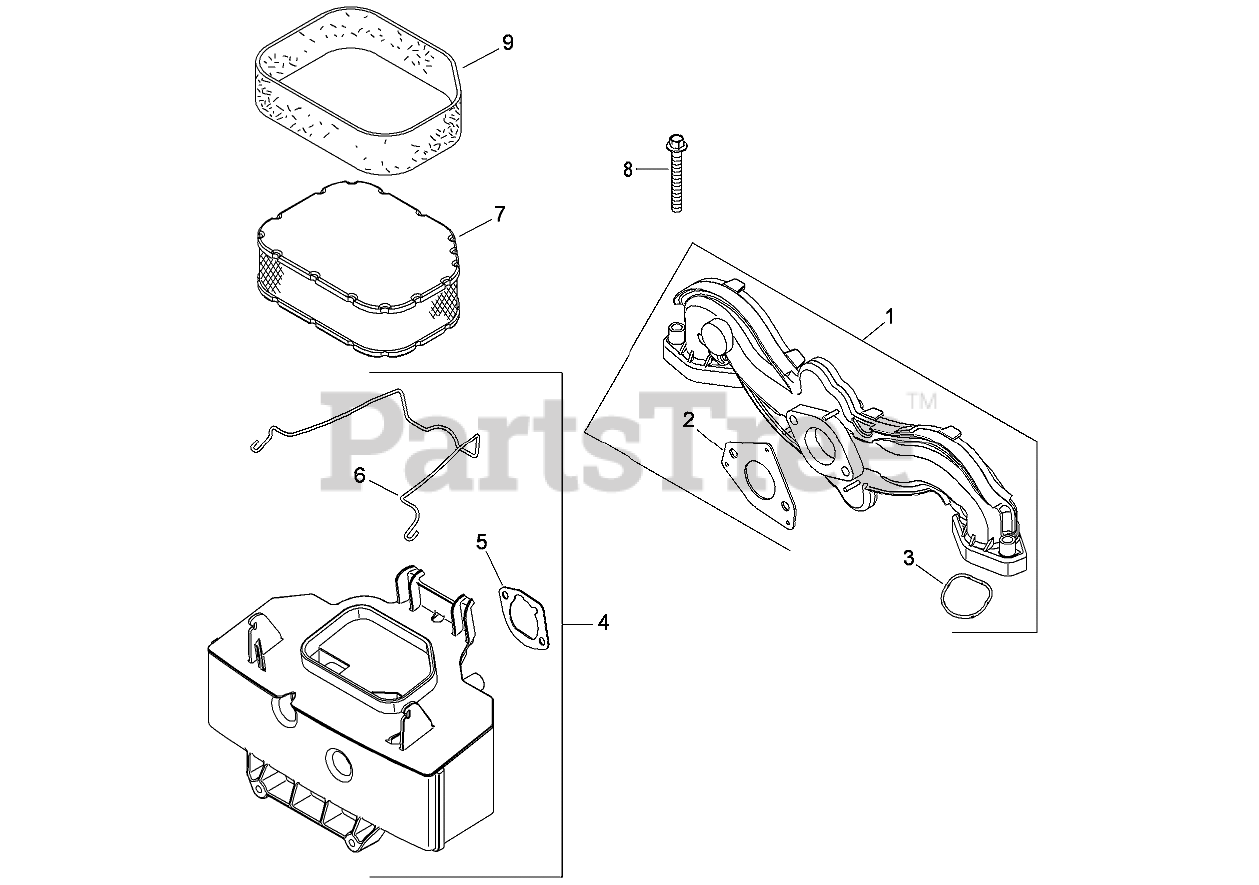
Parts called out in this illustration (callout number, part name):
1	MANIFOLD-INTAKE (INCLUDES 2, 3)
2	GASKET-CARBURETOR
3	O-RING (INTAKE PORT)
4	AIR CLEANER BASE KIT (INCLUDES 5, 6)
5	GASKET-BASE, AIR CLEANER
6	LATCH-ELEMENT, AIR CLEANER
7	ELEMENT-FILTER, AIR
8	SCREW-FLANGE (M6X1.0X40)
9	ELEMENT-CLEANER, PRE
